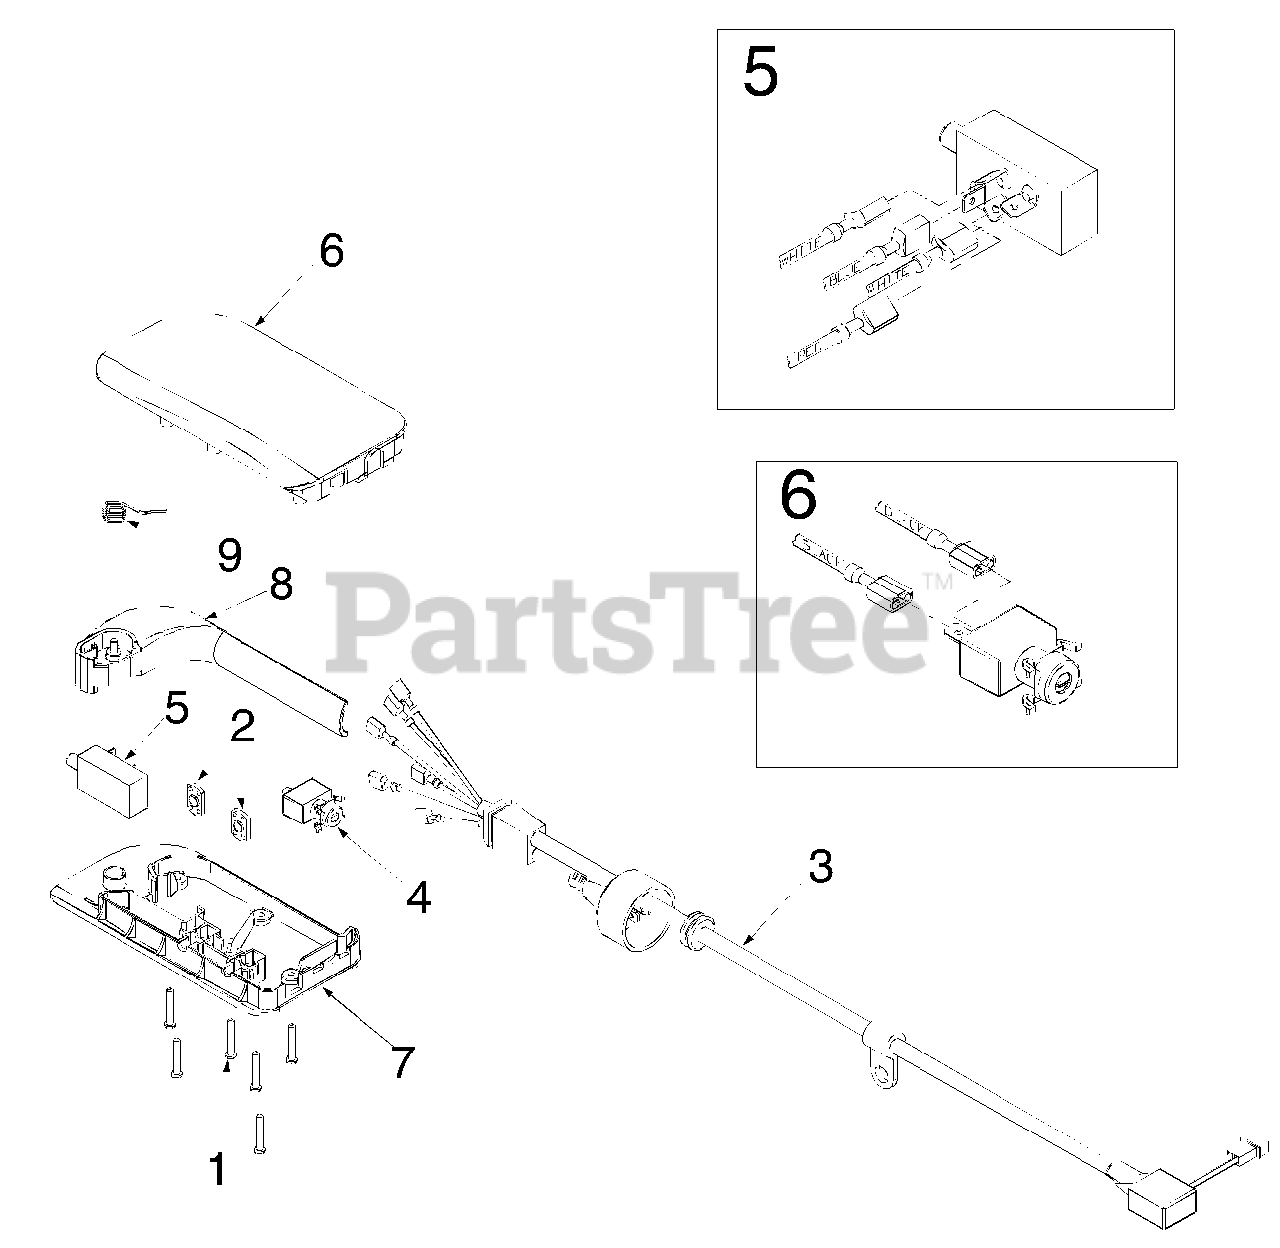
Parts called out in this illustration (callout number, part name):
1	Scr. Hx. Lock #7-19 X 1.00 Lg.
2	Nut Weld Tab 1/4-20 Thd.
3	Cord W/ Plug
4	Circuit Breaker
5	Switch
6	Upper Switch Housing
7	Lower Switch Housing
8	Control Lever
9	Torsion Spring
